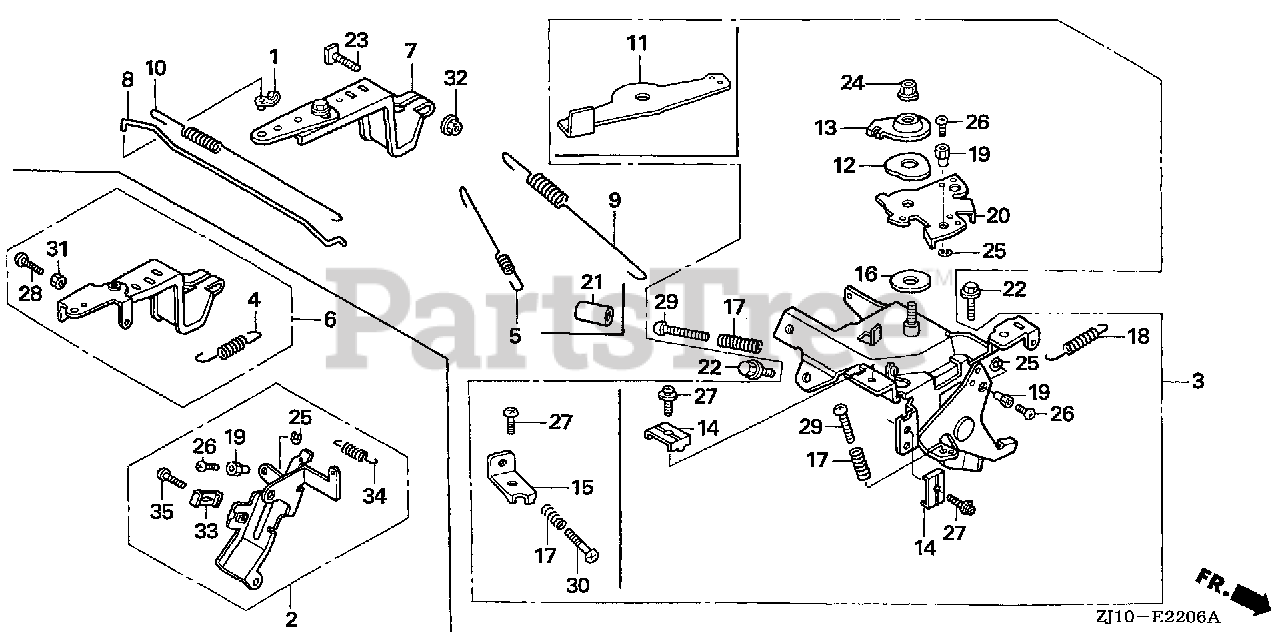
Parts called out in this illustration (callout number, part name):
1	JOINT, ROD
3	CONTROL ASSY. (REMOTE)
5	SPRING, STARTER
7	ARM, GOVERNOR
8	ROD, GOVERNOR
9	SPRING, GOVERNOR
10	SPRING, THROTTLE RETURN
12	SPRING, LEVER
13	WASHER, CONTROL LEVER
14	HOLDER, CABLE
16	SPACER, CONTROL LEVER
17	SPRING, CONTROL ADJUSTING
18	SPRING, CABLE RETURN
20	LEVER, WIRE
22	BOLT, FLANGE (6X12) (CT200)
23	BOLT, GOVERNOR ARM
24	NUT, SELF-LOCK (6MM)
27	SCREW, PAN (5X16)
27	SCREW-WASHER (5X16)
29	SCREW, PAN (5X25)
32	NUT, FLANGE (6MM)
